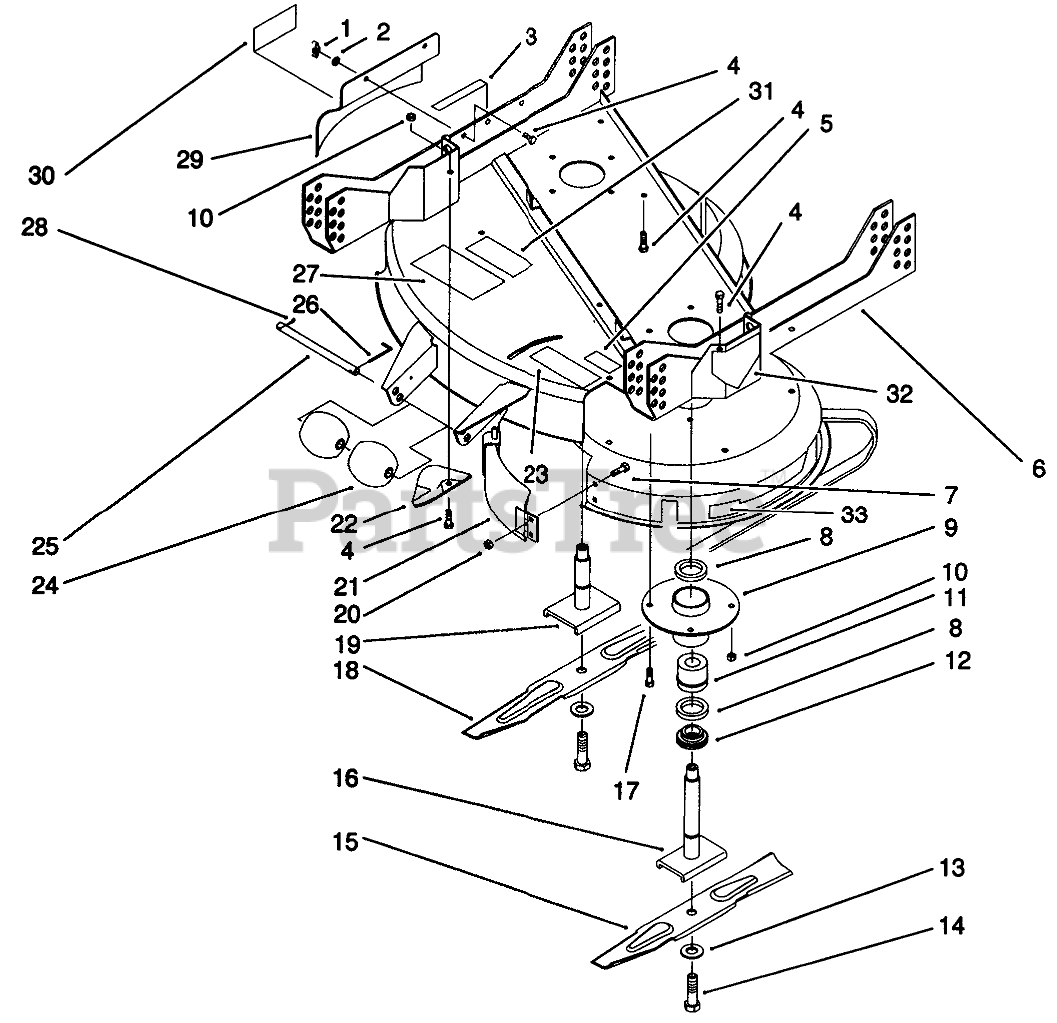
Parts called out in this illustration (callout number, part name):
1	NUT-WING
2	WASHER-LOCK
3	DECAL-DANGER, DEFLECTOR
4	SCREW-HH
5	DECAL-STANDARD, SAFETY
6	Support W.A. (Incl. Ref. #5, 23, 27, & 31-32)
7	SCREW-CARR
8	SEAL-OIL
9	SPINDLE HOUSING
10	NUT-LOCK, NI
11	BEARING ASM
12	SPACER
13	WASHER-LOCK
14	SCREW-BLADE
15	Blade-17"
16	SHAFT-SPINDLE
17	SCREW-SHOULDER
18	Blade-21"
19	SHAFT-SPINDLE
20	NUT-KEPS
21	Front Cover W.A.
22	PLATE-KICKER
23	DECAL - DISCHARGE DOOR
24	ROLLER
25	SHAFT-ROLLER
26	PIN-SPECIAL
27	DECAL-DANGER, THROWN OBJECT
28	PIN-COTTER
29	Cover-Discharge Chute
30	DECAL - DANGER
31	DECAL-TORQUE
32	DECAL-DANGER
33	DECAL - 37"
